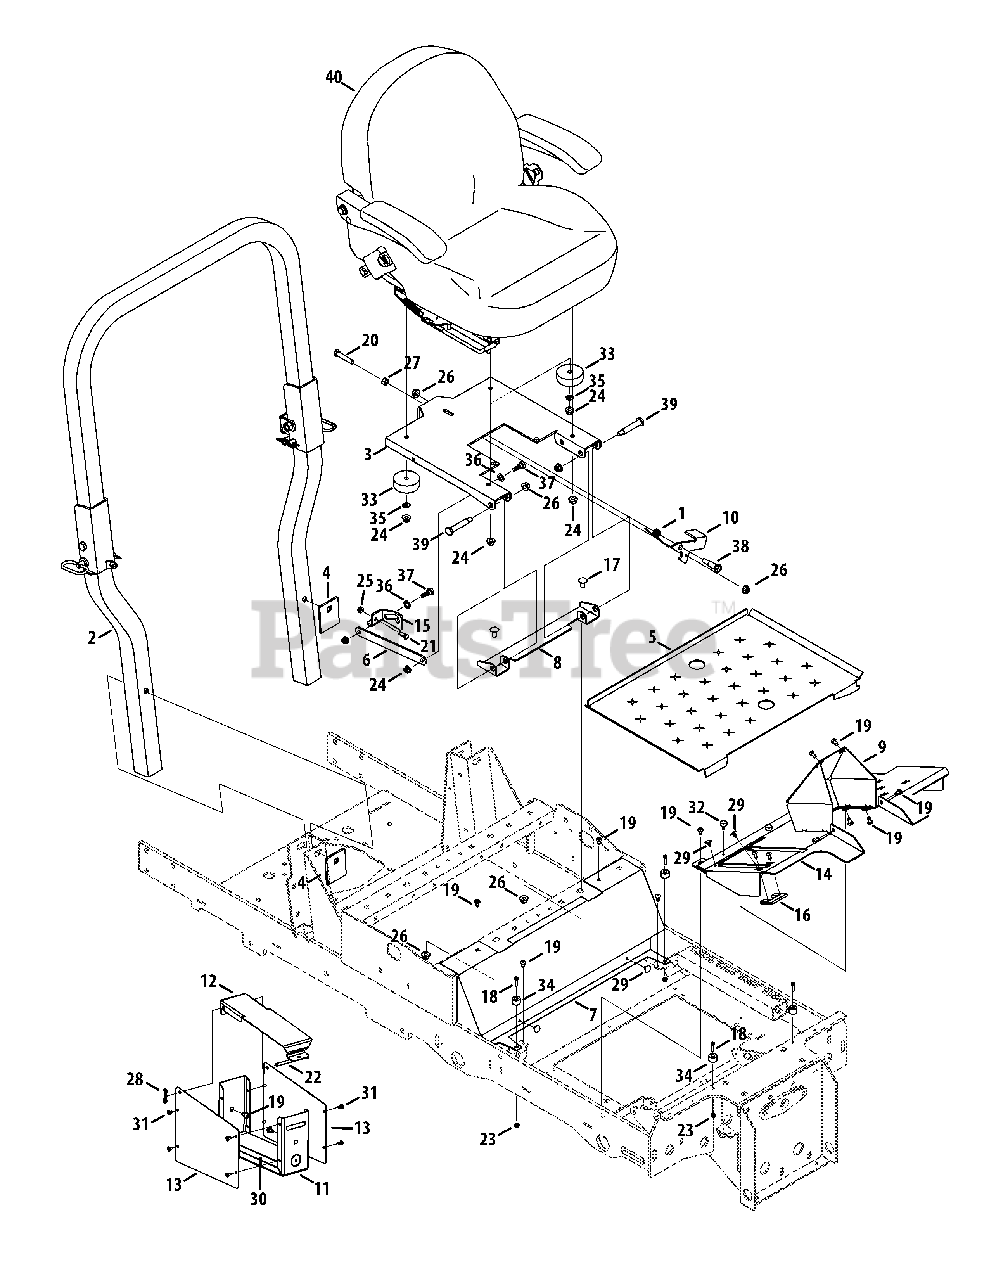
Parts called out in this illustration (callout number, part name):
1	Torsion Spring, .725 x 1.0 x .09
2	Folding ROPS Assembly
3	Seat Mounting Bracket
4	Deck Reinforcement Plate
6	Seat Lockout Bracket
7	Floor Panel Tray
8	Seat Mounting Bracket
10	Seat Lever Latch
12	Storage Box Lid
13	Storage Box Side Panel
15	Seat Lockout Mount
16	Stop Pedal Bracket
17	Carriage Bolt, 3/8-16 x .75
18	Socket Head Screw, 10-24 x .75
19	Screw, 1/4-20 x .5
20	Hex Cap Screw, 3/8-16 x 2.25
21	Hex Cap Screw, 1/4-20 x .75
22	Clevis Pin, .25 x 3.5
23	Nut, #10-24, Hexlock
24	Nut, 5/16-18, Flangelock
25	Nut, 1/4-20, Flangelock
26	Nut, 3/8-16, Flangelock
27	Nut, 3/8-16, Hex
28	Cotter Pin, Bow Tie
29	Clip, .250 Dia. x .500
30	Adhesive Pad
31	Rivet, 3/16 x .325
32	Bumper, .62 Dia. x .3
33	Rubber Bumper, 2.5 x 1.0
34	Rubber Bumper, .75 x .500
35	Washer, .344 x .688 x .065
36	Washer, .469 x .750 x .06
37	Shoulder Screw, .437 x .268, 5/16-18
38	Shoulder Bolt, .50 x .925, 3/8-16
39	Shoulder Bolt, .500 x 2.23, 3/8-16
40	Seat, w/Arm
40	Seat, w/ Suspension (60" only)
